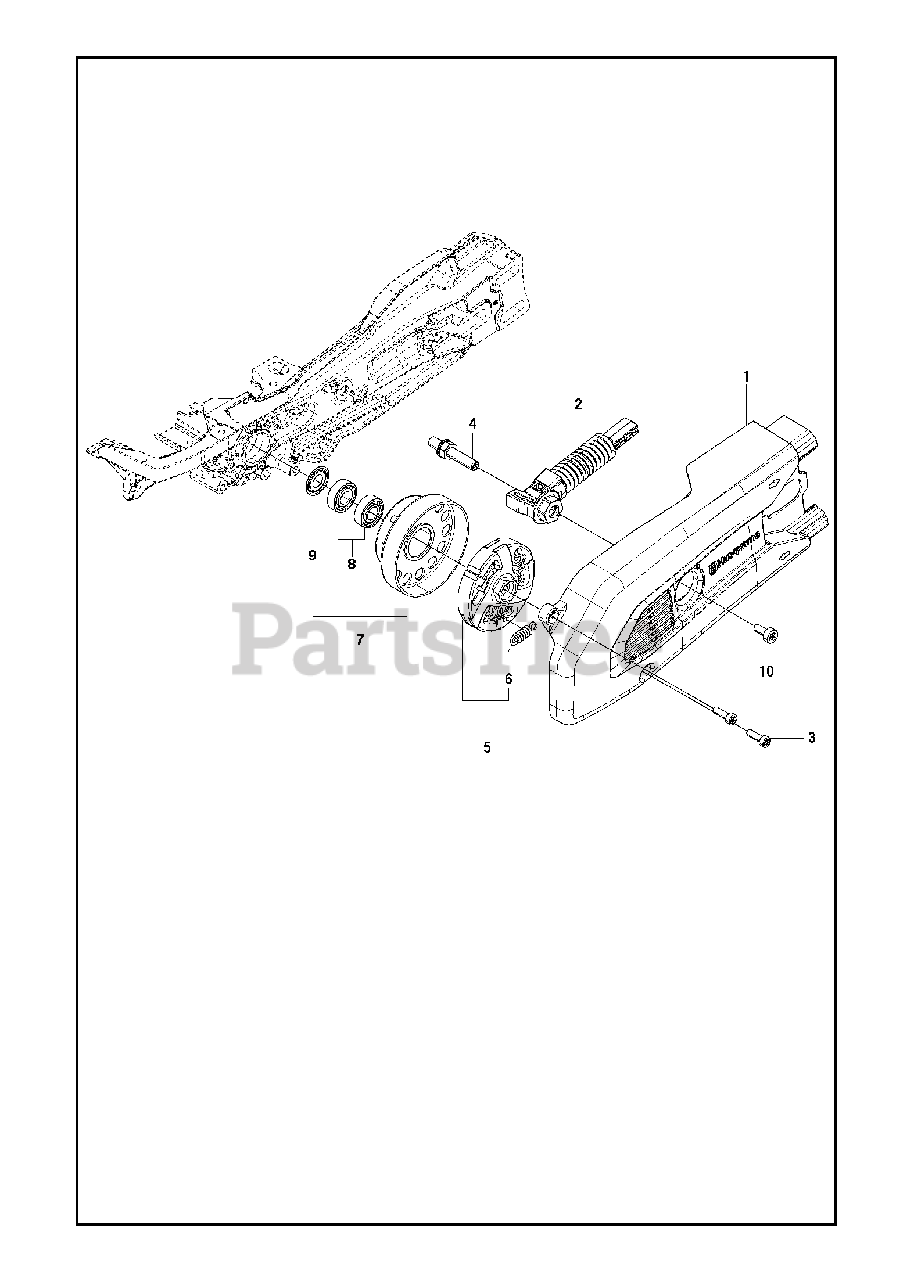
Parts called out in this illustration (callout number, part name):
3	SCREW ITXSCM
5	CLUTCH ASSY
6	CLUTCH SPRING
7	DRIVING PULLEY ASSY"14"""
7	DRIVING PULLEY ASSY"16"""
8	BALL BEARING1 piece per package
10	SCREW ITXSCM
